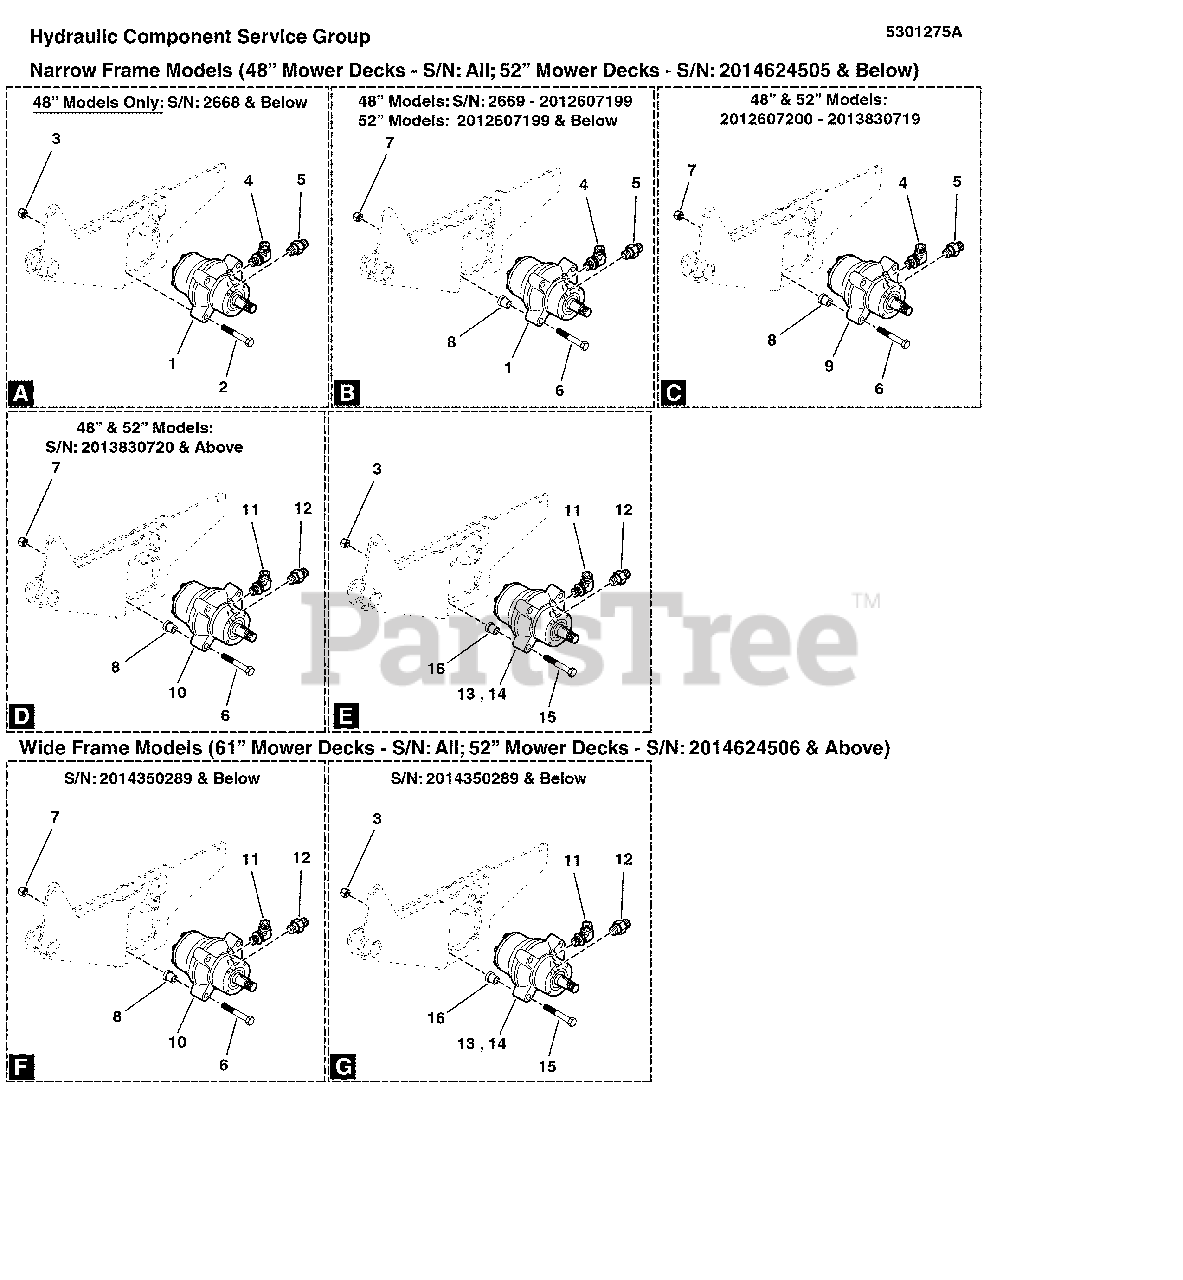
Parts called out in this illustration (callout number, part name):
2	BOLT, 1/2-13 X 2-1/4 PATCH
3	NUT, 1/2-13 SQUARE
4	FITTING, #8 JIC - #8 O-RING, 90 DEG.
5	FITTING, #8 O-RING X #8 JIC, STR
6	BOLT, 1/2-13 X 3-1/2 GD5 YZ
7	NUT, 1/2-13 HEX NYLOCK FLANGE
8	SPACER, .53 X 1.00 X 1.00, CZ
9	MOTOR, WHEEL, HGM-15C-4026
11	FITTING, #10 ORING-#8 JIC, 90D
12	FITTING, #10 O-RING X #8 JIC, STR
13	WHEEL MOTOR, LH, 14.5 CI-TF0240LS080AAKZ
14	WHEEL MOTOR, RH, 14.5 CI-TF0240LS081AAKZ
15	BOLT, 1/2-13 X 3.5, DRI-LOC PATCH
16	SPACER, .53 X 1.00 X 1.00, W/ FLAT, CZ
